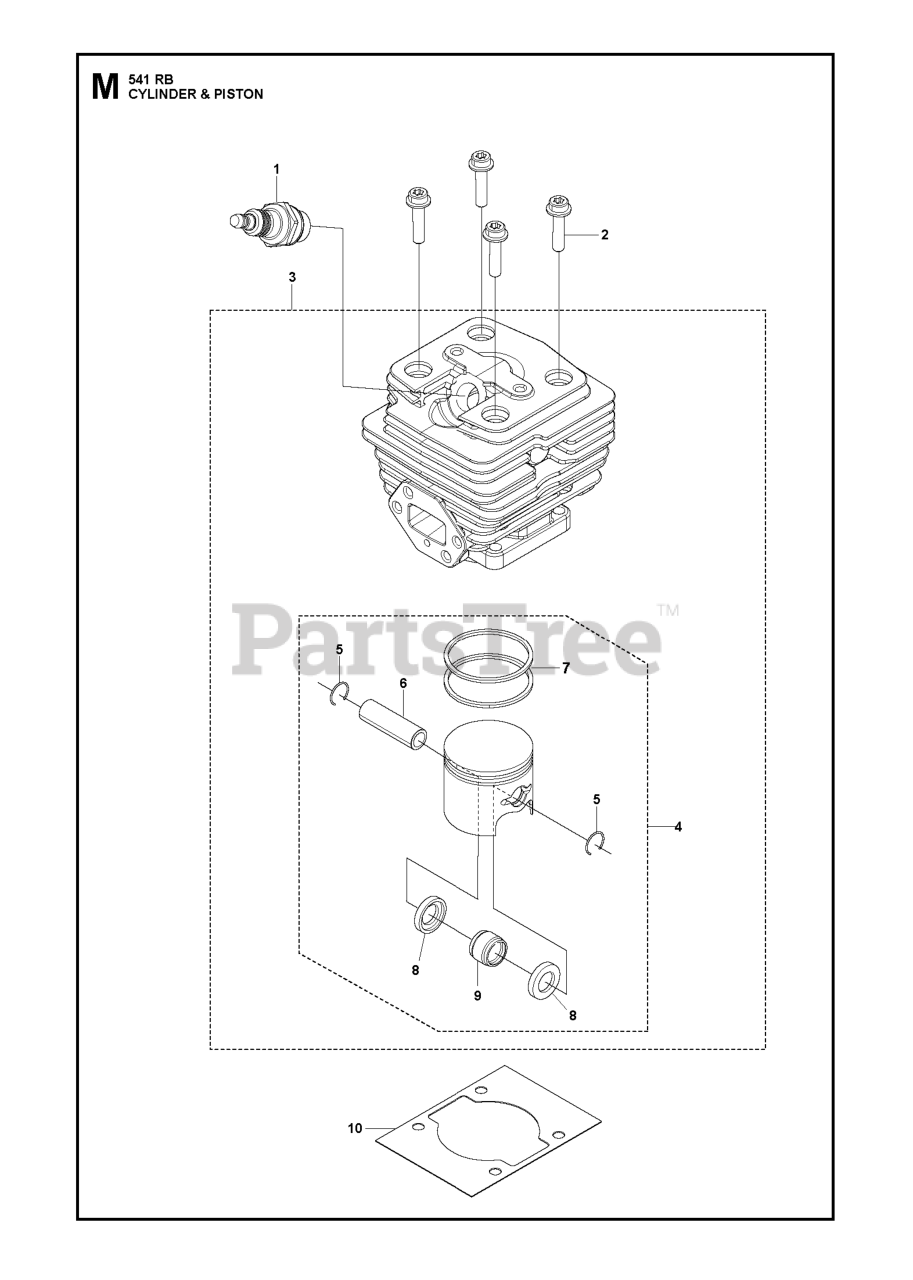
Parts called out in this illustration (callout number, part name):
1	SPARK PLUG RCJ6Y NLA
7	RING, PISTON 2/PK
9	ROLLER BEARING
